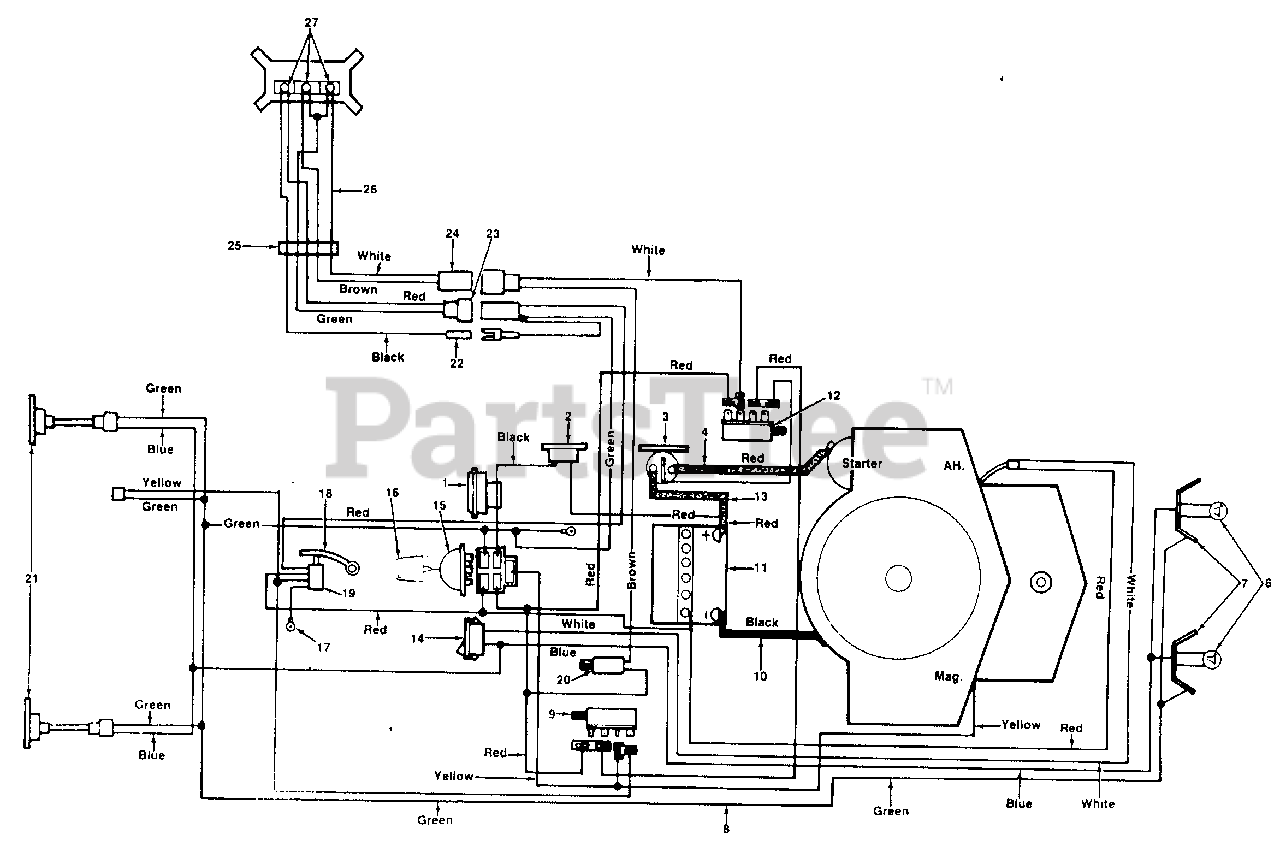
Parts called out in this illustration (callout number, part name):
1	Ammeter
2	Circuit Breaker
3	Solenoid
4	Wire
6	Bulb
7	Socket
8	Wire Harness
9	Safety Switch
10	6 Ga. Black Wire
11	Battery 12V
12	Safety Switch
14	Liaht Switch
15	Ignition Switch
16	Ignition Key
17	Ground Wire
18	Spring Lever
19	Safety Switch
20	Safety Switch
21	Taillight
22	Connector
23	Connector
24	Connector
25	Clamp
26	Wire Harness
27	Bulb
